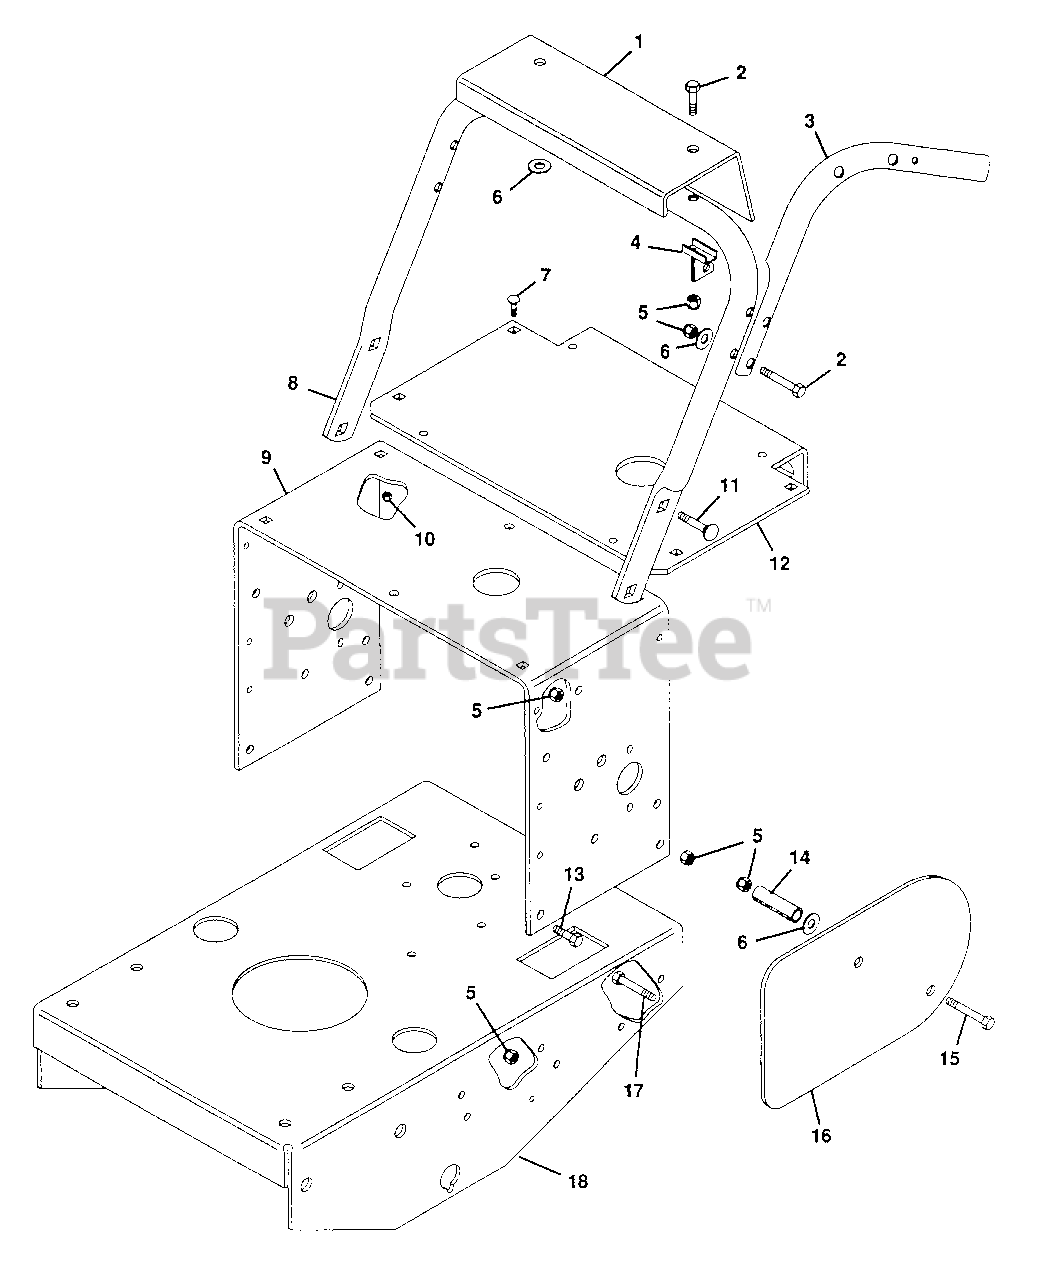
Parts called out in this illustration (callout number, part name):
1	PANEL, SILK SCREEN
2	BOLT, HEX 3/8-16X2.00
3	HANDLEBAR, L.H.
3	HANDLEBAR, R.H.
4	WELDMENT, PTO LEVER MOUNTING
5	NUT, LOCK 3/8-16
6	WASHER, FLAT .406X.812X.065
7	BOLT, 1/4-20X.625 RD HD SQ NK
8	TUBE, HANDLEBAR MOUNTING
9	SUPPORT, HANDLEBAR
10	NUT, LOCK 1/4-20
11	BOLT, 3/8-16X1.00 RD HD SQ NK
12	PLATE, SILK SCREEN
13	BOLT, HEX 3/8-16X1.00
14	BUSH., ST .401X.553X2.25 STL.
15	BOLT, HEX 3/8-16X3.25
16	GUARD, SILK SCREENED L.H.
16	GUARD, SILK SCREENED R.H.
17	BOLT, HEX 3/8-16X1.375
18	FRAME, PRO 32
